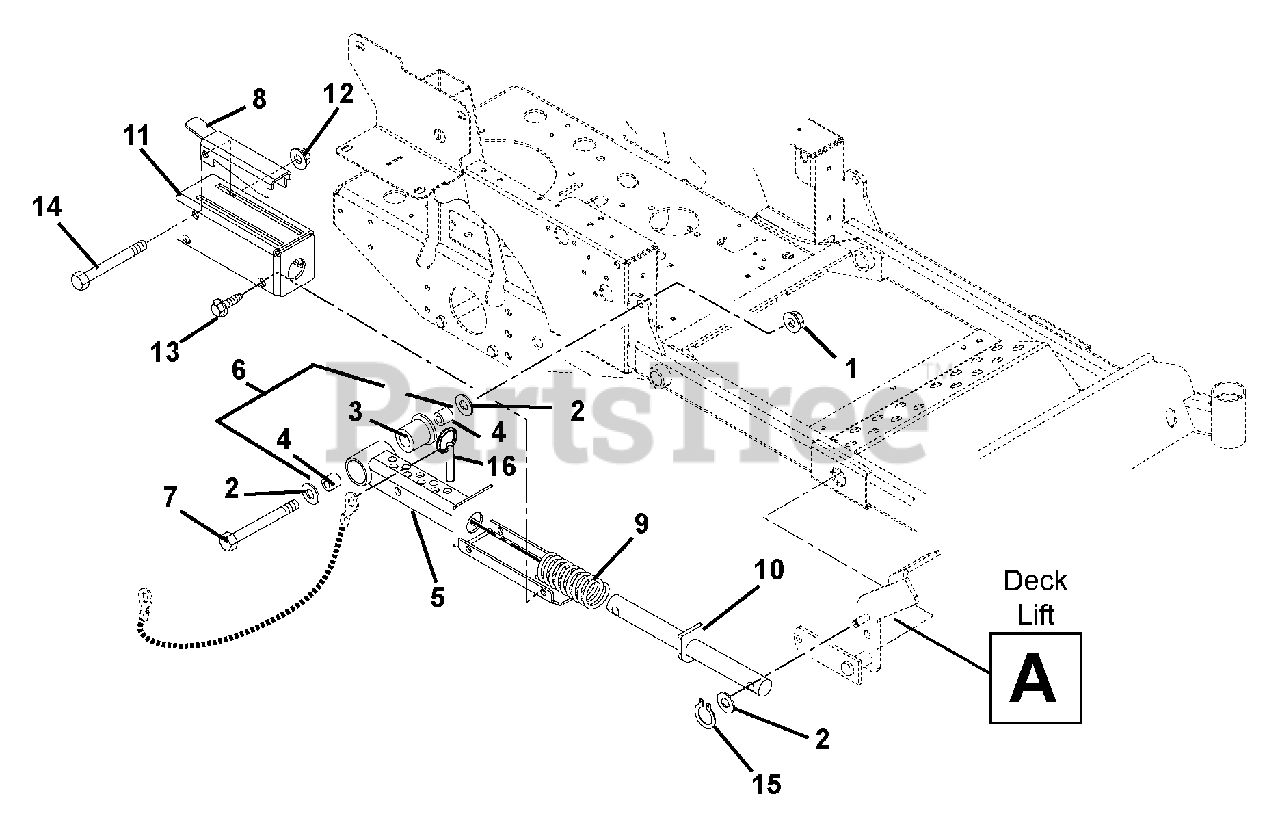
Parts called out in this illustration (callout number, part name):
1	Nut, Locking Top Flange .50-13
2	Washer, Flat Steel .531 x 1.25 x .10
3	Bearing, Pedestal Powdered Metal
4	Bearing, 1.00 x 1.12 x .75
5	Weldment, Mechanical Lift
6	Assembly, Mechanical Lift
7	Bolt, Round Head Square Neck .50-13 x 3.75 Grade 5
8	Lock-Up, Mechanical Lift
9	Spring, Compression 1.13 x 1.48 x 5.10 (056, 314)
9	Spring, Compression 1.13 x 1.47 x 5.10 (065)
10	Weldment, Mechanical Lift Shaft
11	Weldment, Mechanical Lift Cover
12	Nut, Nyloc Flange 3/8-16
13	Screw, Tapping .38-16 x .50 Hex Washer Head
14	Bolt, Hex .38-16 x 3.25 Grade 5
15	Ring, Retaining External .50 x .05
16	Pin, Spring Ball .375 O.D. x 1.50
